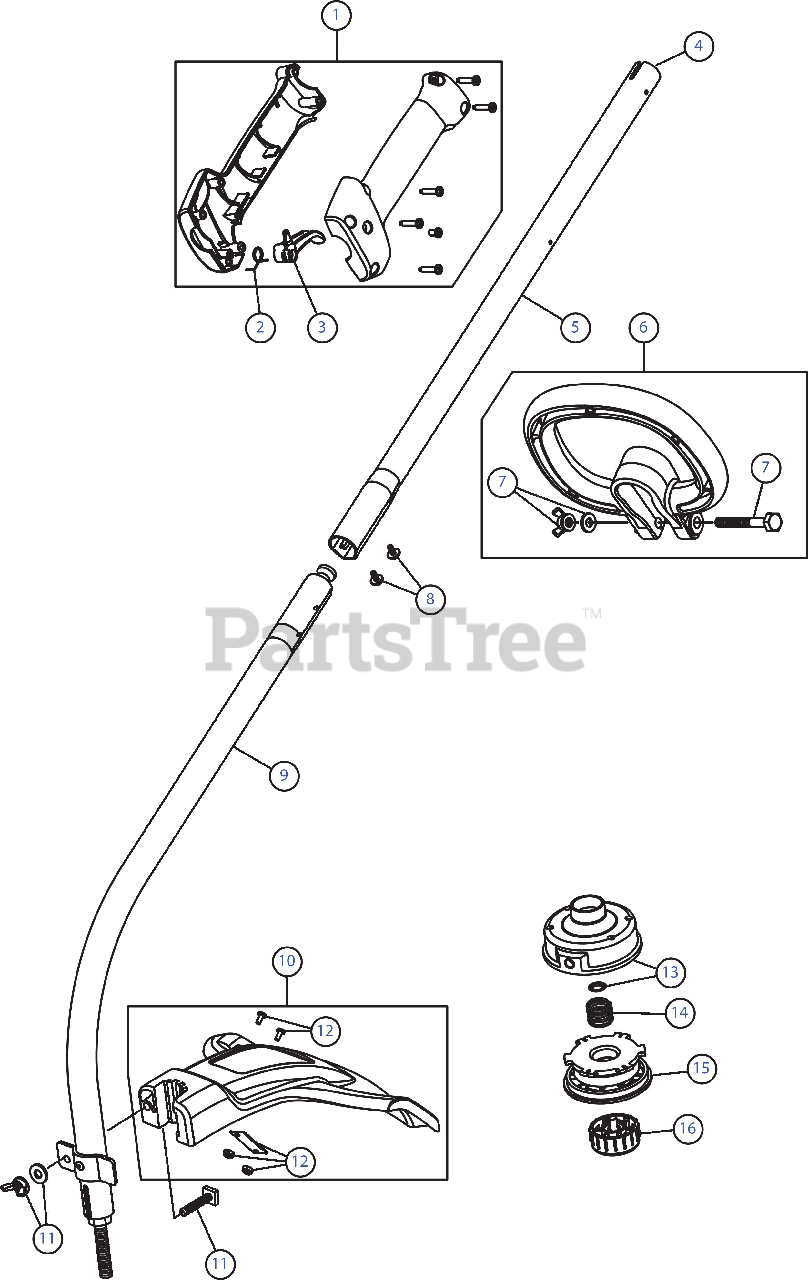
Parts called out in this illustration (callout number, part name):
1	Throttle Housing Assembly (Incl. 2 & 3)
2	Throttle Trigger Spring
3	Throttle Trigger
4	Flexible Drive Shaft
5	Upper Shaft Housing Assembly
6	D-Handle (Incl. 7)
7	D-Handle Hardware
9	Lower Shaft Housing Assembly
10	Shield Assembly (Incl. 11 & 12)
11	Shield Mounting Hardware
12	Blade Assembly
13	Outer Spool Assembly (with Retainer)
15	Inner Reel
16	Bump Head Knob Assembly
